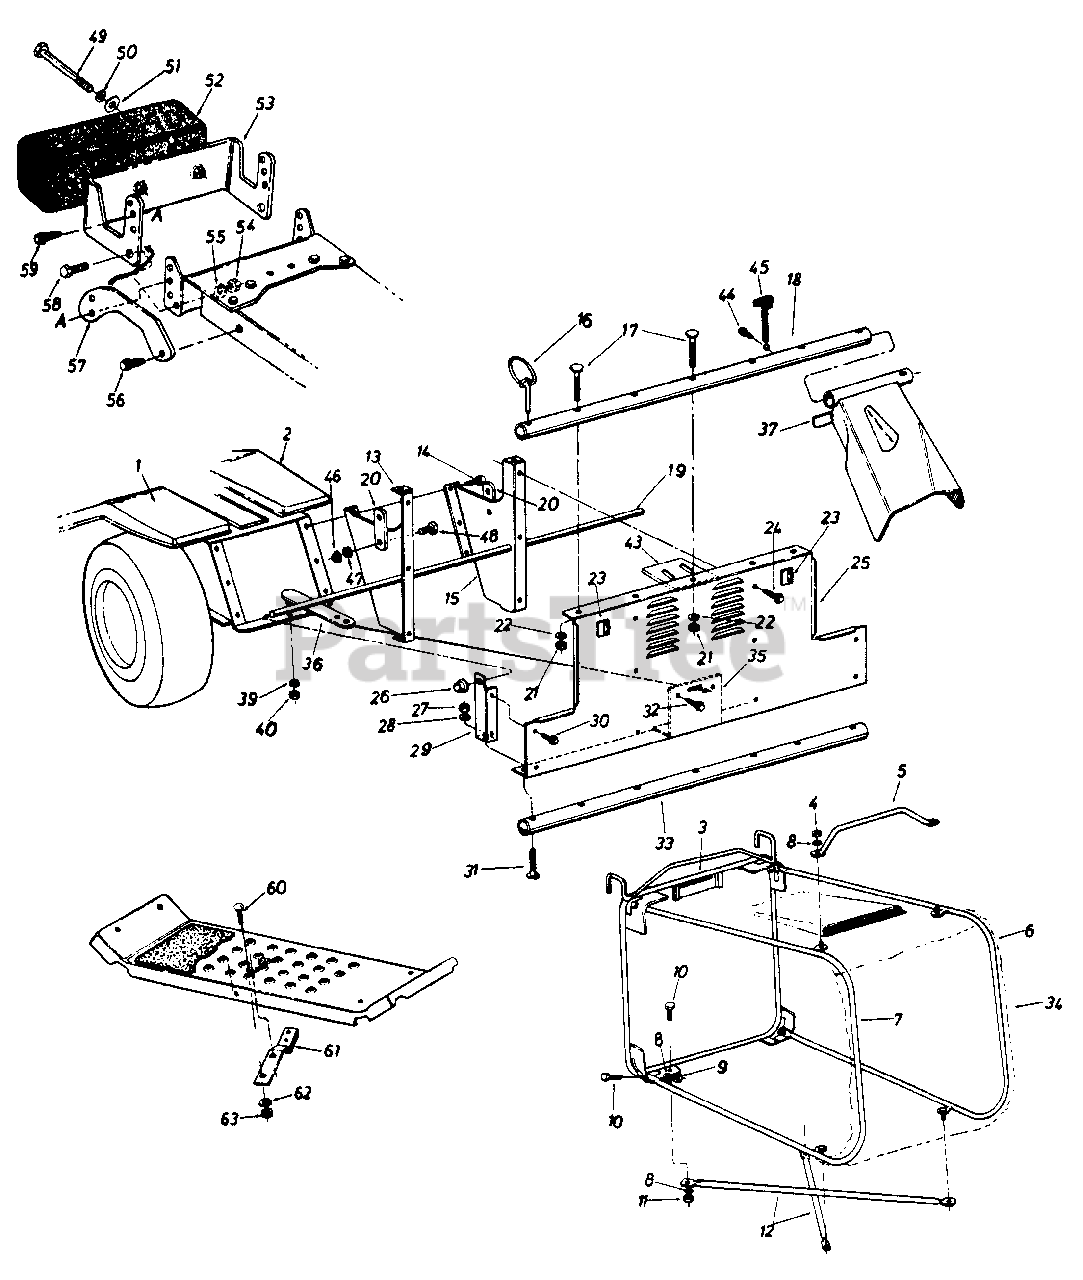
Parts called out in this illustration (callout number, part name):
3	Grass Catcher Frame Ass'y.
4	Hex Cent. L-Nut 1/4-20 Thd.
5	Grass Catcher Handle
9	Hex Cent. L-Nut 1/4-20 Thd.
10	Hex Bolt 1/4-20 x .62" Lg.
11	Hex Cent. L-Nut 1/4-20 Thd.
12	Bottom Cross Brace
13	Grass Catcher Support Brkt. -L.H.
14	Hex Wash. Hd. Self-Tap Scr. 5/1 6-1 8 x .751" Lg.
15	Grass Catcher Support Brkt. -R.H.
16	Klick Pin
17	CuNed Carr. Bolt 5/16-18 x 1 75n Lg.
18	Grass Catcher Support Tube
19	Tubing 38" I.D. x 39 .75" Lg.
20	Fender Support Brkt.
21	Hex Nut 5/16-18 Thd.
22	L-Wash. 5/16" I.D.
23	Safety Switch
24	Hex Wash. Hd. Self-Tap Scr. 1/4-20 x .50" Lg.
25	Grass Catcher Adapter
26	Cap Speed Nut 1/2" Rod
27	Hex Nut 5/16-18 Thd.
28	L-Wash. 5/16" I.D.
29	Chute Extension Support Brkt.-L.H.
30	Hex Wash. Hd. Self-Tap Scr. 1/4-20 x .50" Lg.
31	CuNed Carr. Bolt 5/16-18 x 1.75" Lg
32	Hex Wash. Hd. Self-Tap Scr. 1/4-20 x .50" Lg.
33	Tubing 1.00" I.D. x 40.25"
34	Grass Catcher Bag
35	Hitch Bracket
40	Hex Jam Nut 1/2-13 Thd.
43	Grass Catcher Support Plate
44	Hex AB-Tap Scr. 1/4-20 x .62" Lg.
45	Spring Latch Ass'y.
46	Hex Nut 1/4-20 Thd.
47	L-Wash. 1/4" I.D.
48	Hex Bolt 1/4-20 x .50" Lg.
49	Hex Bolt 3/8-16 x 4.50" Lg.
50	Bell-Wash. .400" I.D. x .88" O.D.
51	Fl-Wash. .390" I.D. x 1.12" O.D.
52	Front Counterweight
53	Weight Bracket Ass'y.
54	Hex Jam Nut 7/16" Thd.
55	L-Wash. 7/16" I.D.
56	Hex Wash. AB-Tap Scr. 5/16 x 1 on Lg
57	Weight Brkt. Tie Strap
58	Hex Bolt 7/16-20 x 1.0" Lg.
59	Hex Wash. AB-Tap Scr. 5/16 x 1.0" Lg
60	Carr. Bolt 1/4-20 x .62" Lg.
61	Blade Brake Ass'y.
62	L-Wash. 1/4" I.D.
63	Hex Nut 1/4-20 Thd.
